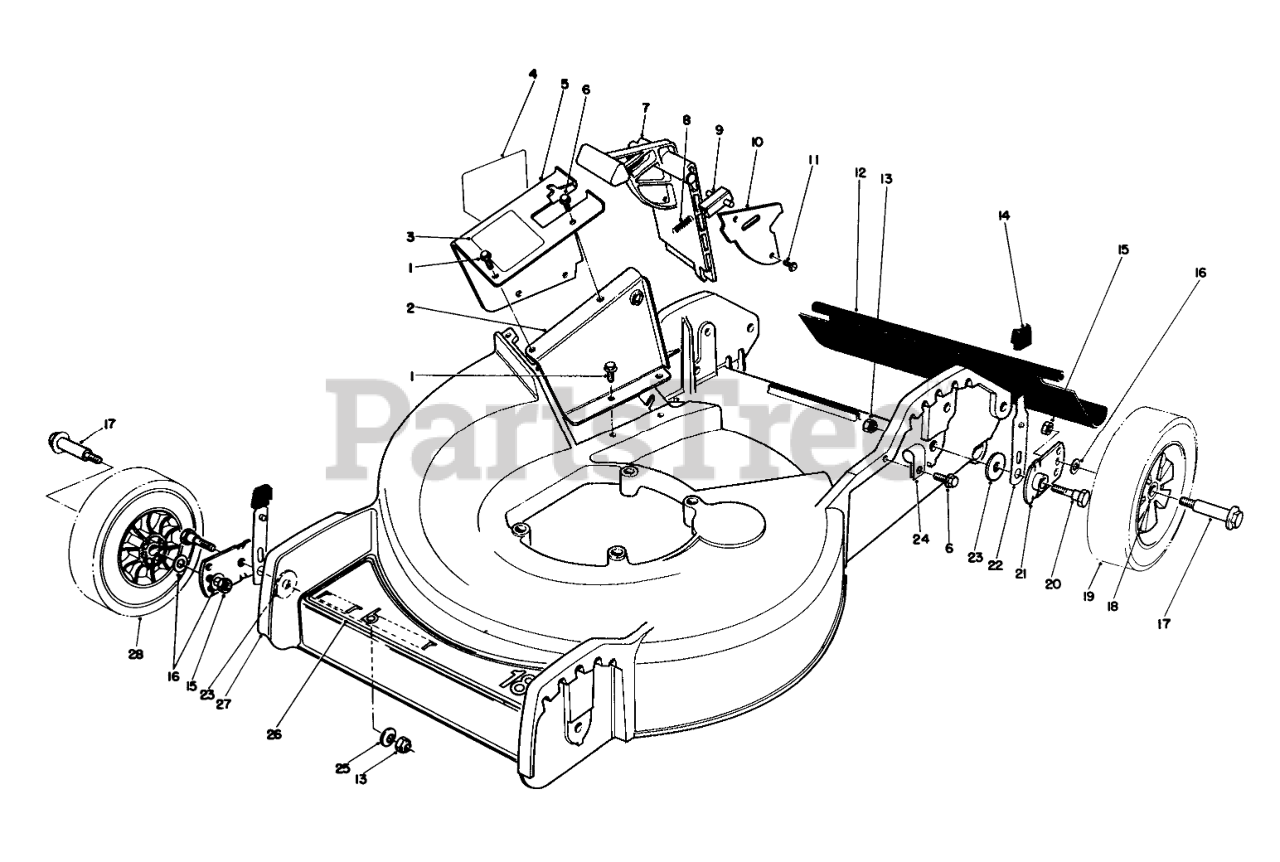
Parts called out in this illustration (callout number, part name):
1	SCREW
2	Tunnel-Inner
3	CAUTION DECAL
4	Decal-Danger
5	Tunnel-Outer(Incl. Ref. #3 & 4)
6	SCREW
7	Door Mulching
8	SPRING-COMPRESSION, LATCH
9	Door Latch
10	Cover Door
12	SHIELD - TRAILING
13	NUT-LOCK, NI
14	KNOB-ARM
15	Nut
16	WASHER
17	BOLT-WHEEL
18	BUSHING
19	Wheel & Tire Assembly (Incl. Ref. #18)
20	PIVOT SCREW
21	PIVOT ARM ASSY
22	SPRING ARM ASM
23	PIVOT WASHER
24	CLAMP-R
25	WASHER-BELLEVILLE
26	DECAL-DECK
27	Housing
28	Wheel & Tire Assembly (Incl. Ref. #18)
